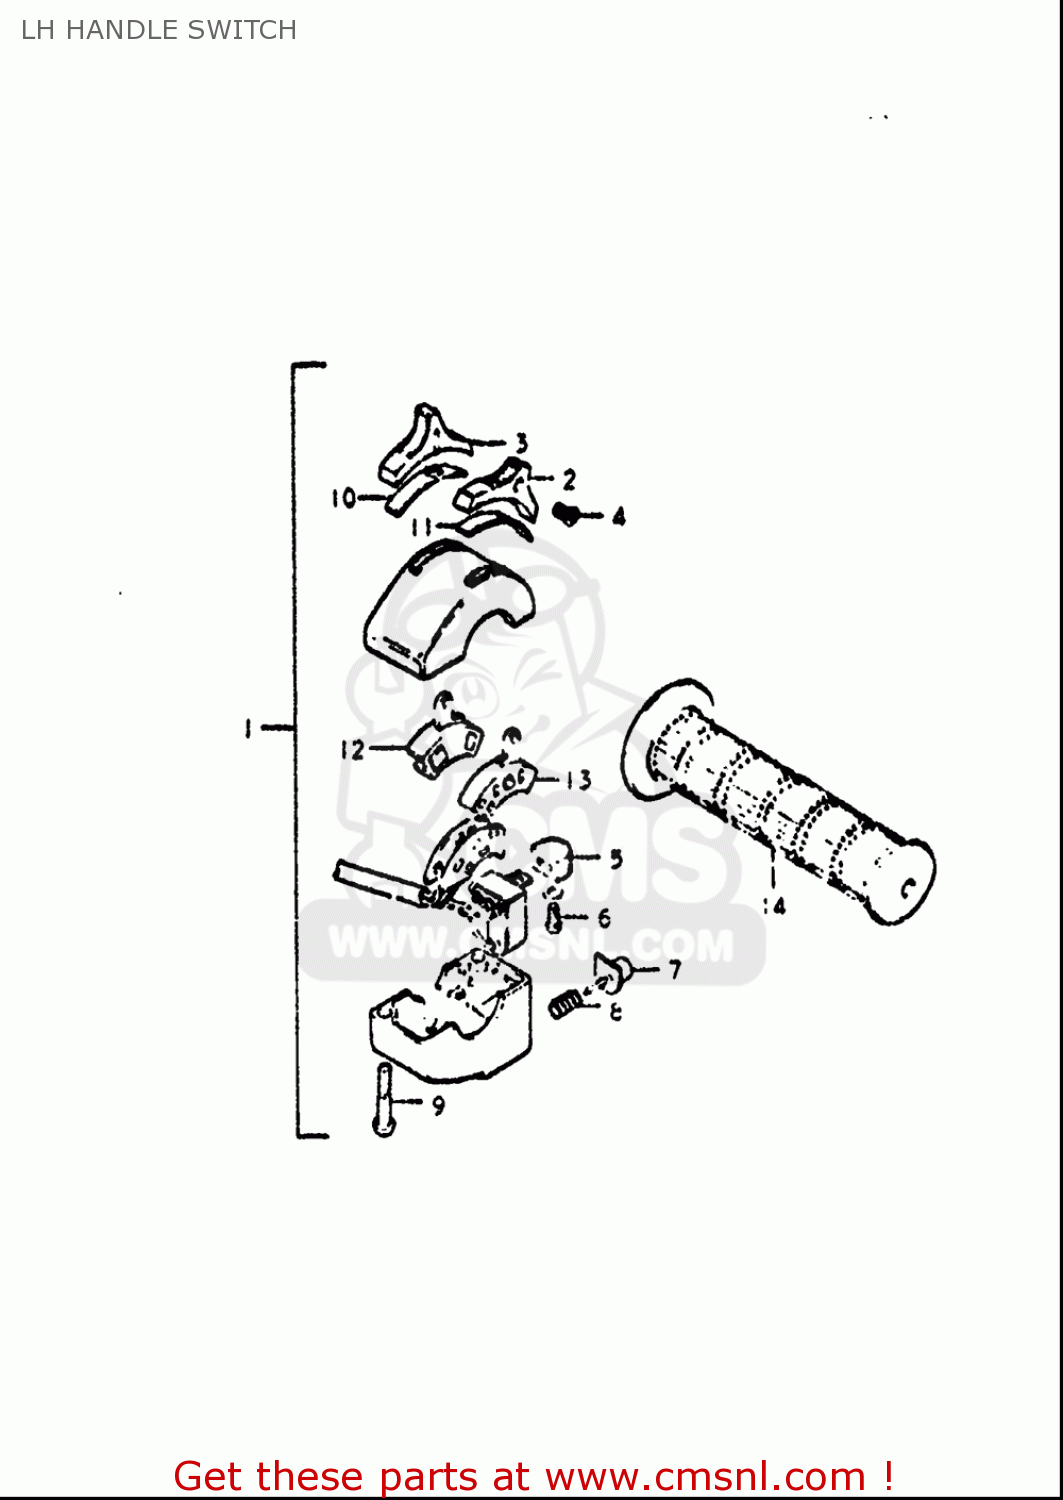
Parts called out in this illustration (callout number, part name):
2	KNOB,HANDLE SWITCH
3	KNOB
4	SCREW
6	SCREW
7	BUTTON,HORN
8	SPRING,BUTTON
9	SCREW
10	PLATE,SWITCH KNOB
13	BLOCK, LIGHTING SWITCH
14	GRIP,L
